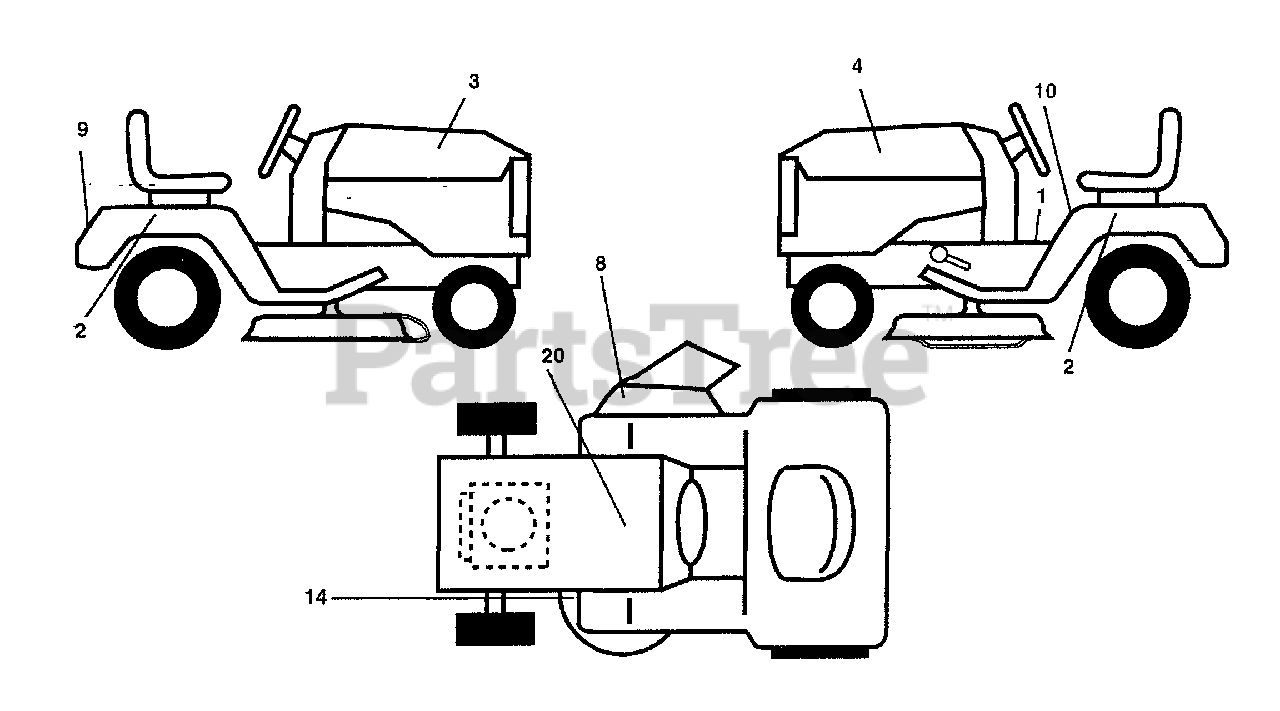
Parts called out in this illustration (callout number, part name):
1	Decal Oper Step Thru E/F
2	Decal Fender Auto Husq. Radius
3	Decal Hood RH
4	Decal Hood LH
8	Decal Warning
9	Decal Fender Husq
10	Decal Fender Danger E/F
14	Decal V-Belt Schematic
20	Decal Bat Dan/Psn
